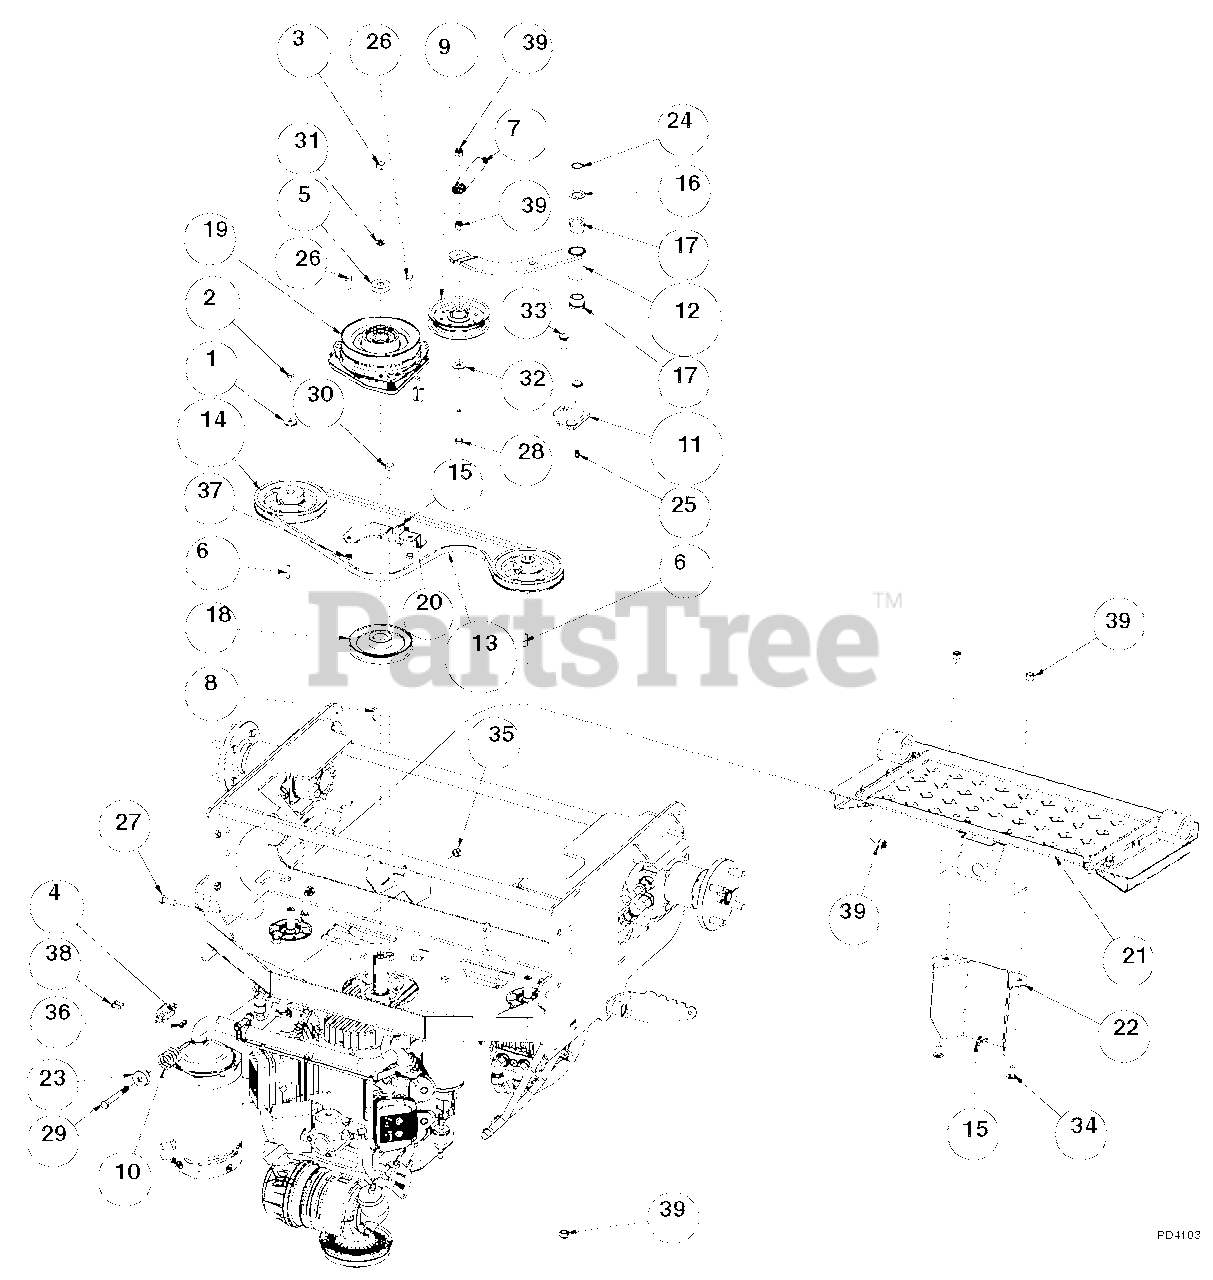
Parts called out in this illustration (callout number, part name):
1	Washer, .250 Wide Heavy Flat Y
2	Bolt, M6 x 1.00 x 10 Hex 8.8 Y
3	Bolt, 7/16-20 x 3.00 Hex 5 Y
4	Switch (N.0.)
5	Spacer, .468 x 1.38 x .375 Y
6	Key, M5 x M5 x M30 RD
7	Spring, External .900 x .135 x 4.50 Y
8	Key, .250 x .250 x .995 TPR
9	Pulley, V-Belt 4.00 x .379 w/Bearing
10	Spring, COM 1.22 x .162 x 2.50 Y
11	Weldment, Pivot Idler Mount
12	Weldment, Idler Arm
13	Belt, Pump Drive
14	Assembly, Pump Pulley w/Set Screw
15	Cable Tie, .15 x 8.50
16	Bushing, MACH .750 x 1.25 x .048 Y
17	Bearing, FLG .750 x 1.00 x .750 BRNZ
18	Pulley, V-Belt 4.78PD x 1.000 W/KEY
19	Clutch Assy, Ogura
20	Plate, Clutch Dog
21	Assembly, Foot Plate (See Foot Plate on page 20.)
22	Cover, OPC
23	Washer, Spring Y
24	Snap Ring, .750 x .042 External
25	Fitting, 1/4-28 STRGT Grease Zerk
26	Bolt, 5/16-18 x .750 Hex 5 Y
27	Bolt, 3/8-16 x 1.00 Hex 5 Y
28	Bolt, 3/8-16 x 2.50 Hex 5 Y
29	Bolt, 3/8-16 x 3.25 Hex 5 Y
30	Bolt, 7/16-14 x .750 Hex 5 Y
31	Washer, .438 Medium Spring Lock Y
32	Washer, .375 Regular Flat Y
33	Bolt, 3/8-16 x 1.00 Carriage Grade 5 Y
34	Bolt,3/8-16x3/4 Car Grade 5 LN Y
35	Nut, 3/8-16 Standard Hex Grade 5 Y
36	Locknut, 10-24 Nyloc Y
37	Locknut, 5/16-18 Nyloc Y
38	Screw, 10-24 x .625 PAN PHL MACY
39	Locknut, 3/8-16 Nyloc Y
